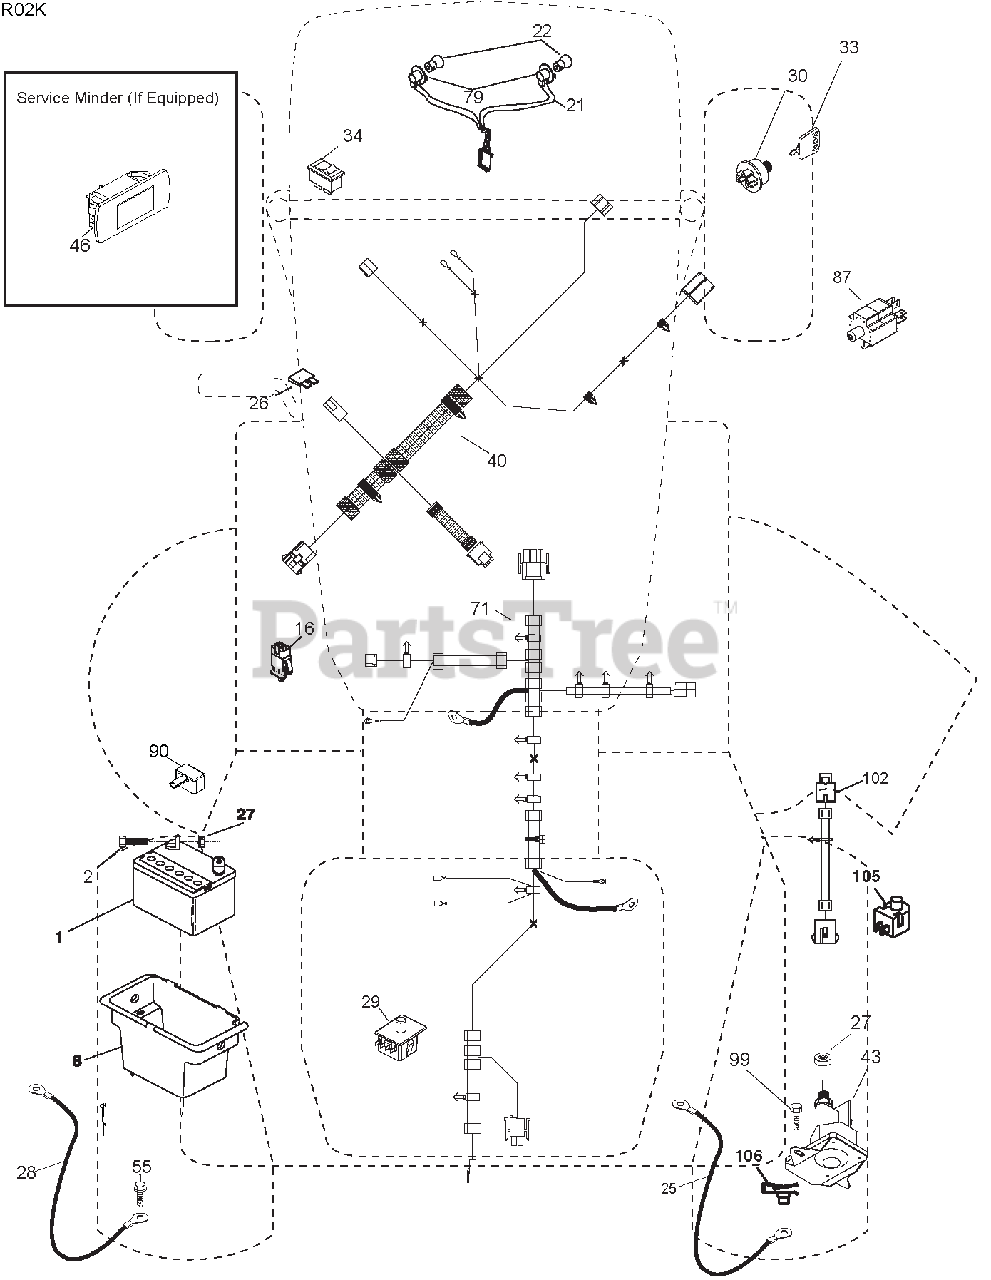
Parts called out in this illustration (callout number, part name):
1	BATTERY.12.VOLT.28.AMP.WET
2	BOLT.HEX.HD.1/4-20UNC X 3/4
8	BOX.BATTERY.MNT.REAR.LT.TEX.BL
16	SWITCH.INTERLOCK.NONO.GRAY
21	HARNESS ASM.LIGHT.22"(4152J)
22	BULB.LIGHT.#1156
25	CABLE STARTER 6 G4. BL/RED14.5
26	FUSE.20 AMP.
27	Nut, Keps Hex 1/4-20 unc
28	CABLE.BLACK.22"REAR BATT.TEX
29	SWITCH.SEAT.DELTA.OPC.9LB.
30	SWITCH.IGN.DLTA.P-IN.ROS
33	KEY/CHAIN.BLISTER PACK.GEN.USA
34	SWITCH.LIGHT/RESET.B/B/RED.
40	HARNESS IGN ELEC RELAY
43	SOLENOID.W/BRASS PLUNGER.2005
55	SCREW.5/16-18X3/4.SMGML.TAP/R
71	HARNESS.IGN.CHASSIS.TEX
79	SOCKET ASM.BULB.TWISTLOCK
87	SWITCH.INTRLCK.CLUTCH.CABLE.TX
90	COVER TERMINAL BATTERY FR. TEX
102	HARNESS.PIGTAIL
105	SWITCH.REVERSE.TT.PEDAL CONTRO
